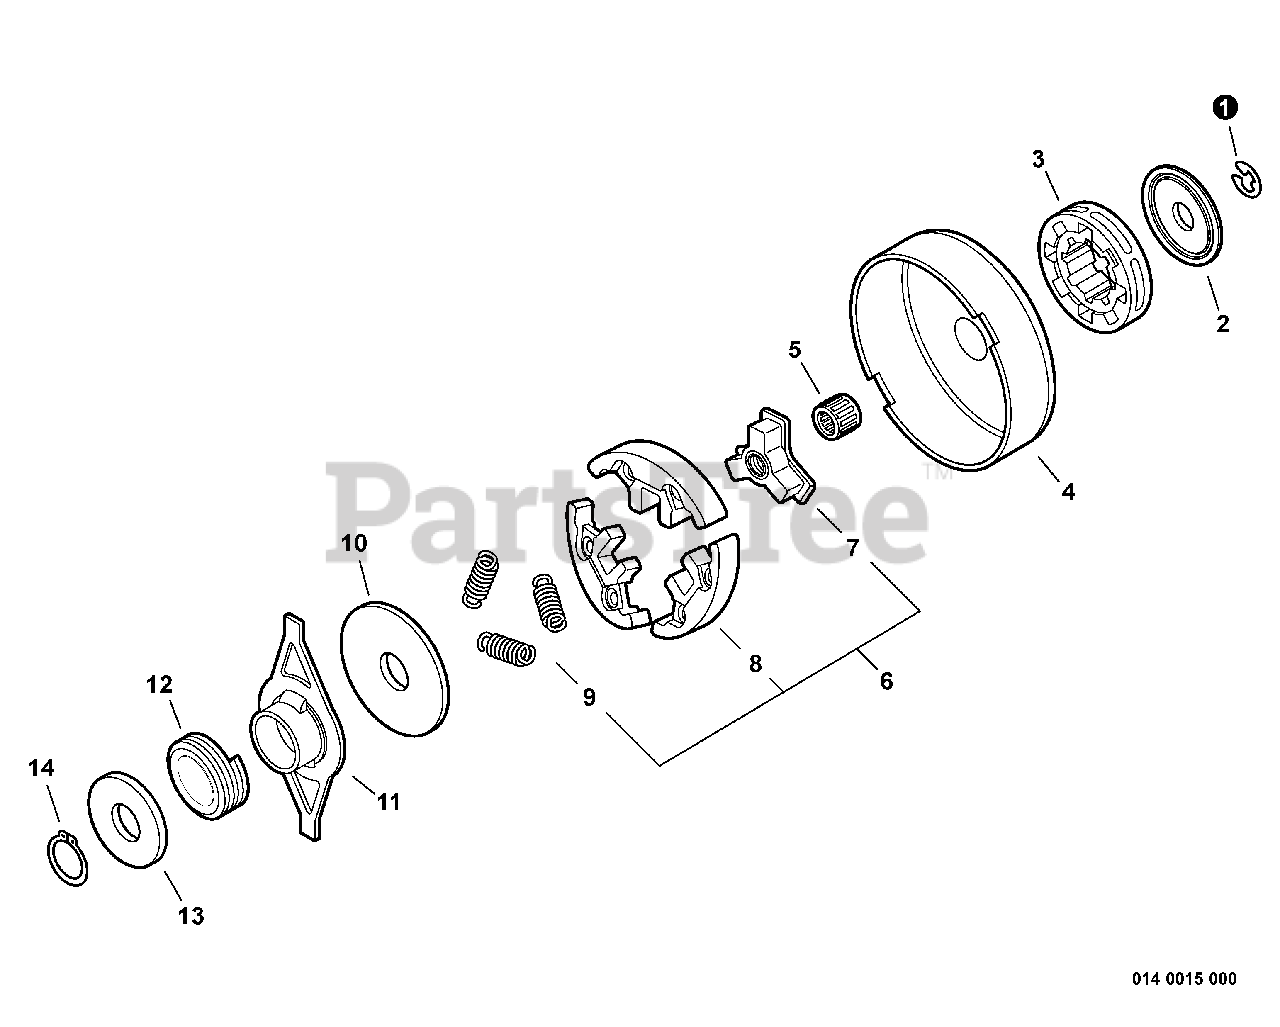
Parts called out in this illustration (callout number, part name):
1	RING, SNAP Ø8 T: 1.2
2	WASHER 10
3	SPROCKET, 0.325 RIM
4	DRUM, CLUTCH
5	BEARING, NEEDLE 10
6	CLUTCH ASSY
7	HUB, CLUTCH
8	SHOE SET, CLUTCH (3PCS)
9	SPRING, TENSION
10	PLATE, CLUTCH
11	COLLAR 15×19×73
12	GEAR, WORM
13	WASHER 15.5×22.5×0.5
14	RING, RETAINING 15
